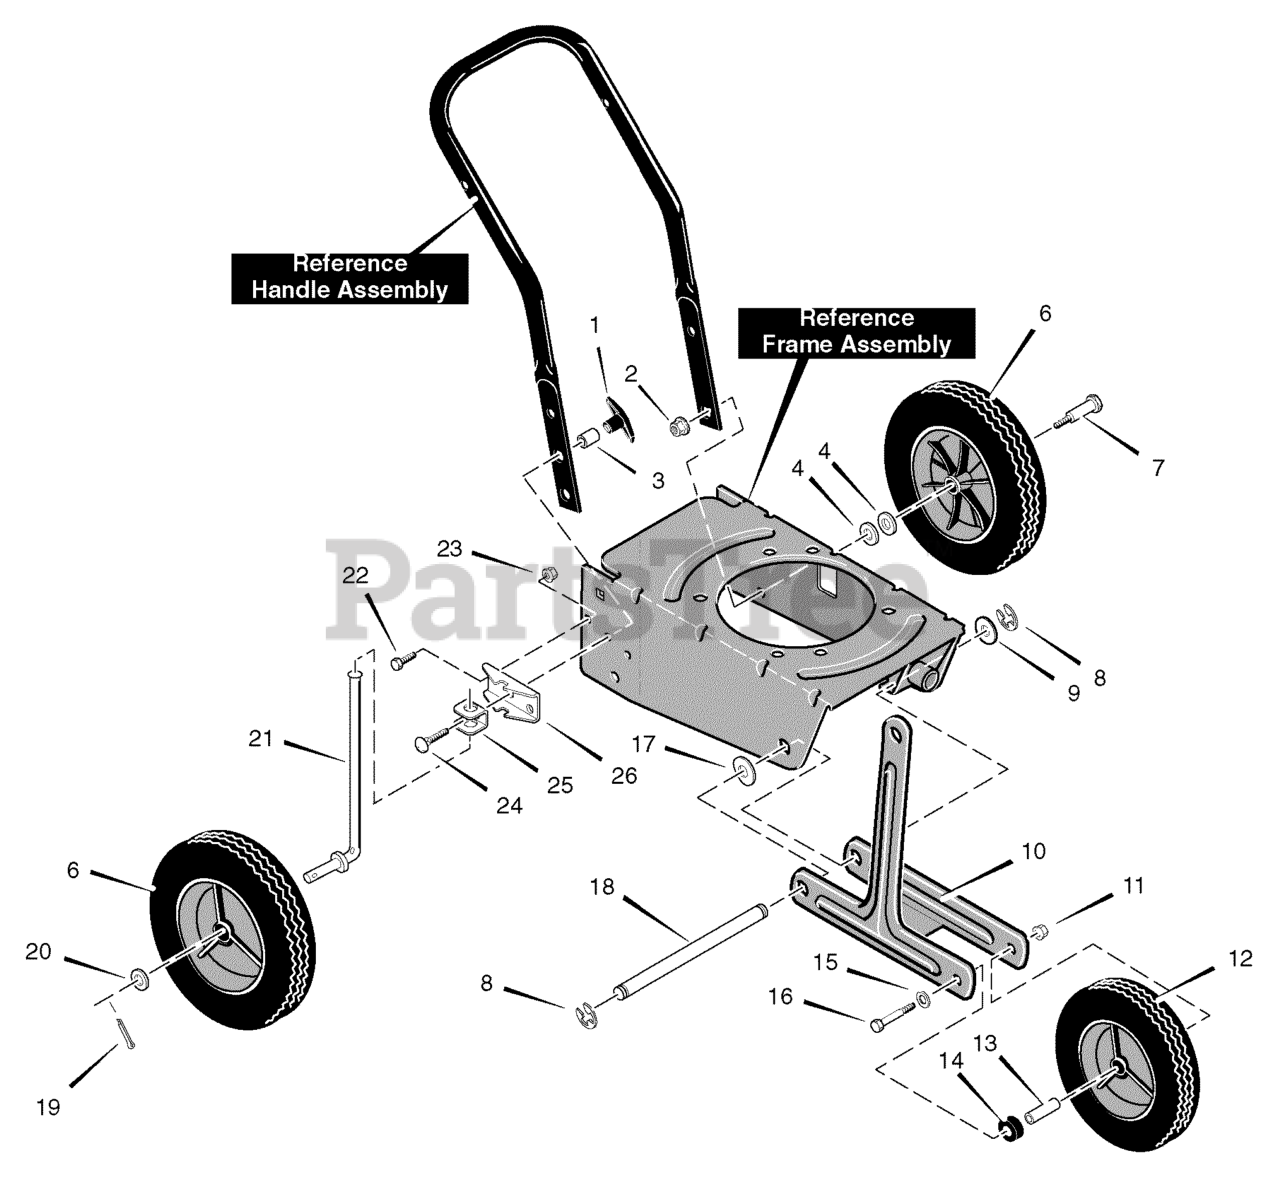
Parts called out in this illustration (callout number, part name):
1	Knob, Wing
2	Locknut, Flange
3	Spacer, Sleeve
4	Washer
6	Tire & Rim
7	Bolt, Shoulder
8	Ring, Ret E.
9	Flat washer
10	Arm, Front Wheel
11	NUT, 5/16-18
12	Tire & Rim
13	Spacer, Sleeve
14	Washer, Nylon
15	Flat washer
17	Spring Washer
18	Rod, Axle Front
19	Pin, Cotter
20	Washer
21	Rod, Wheel Support
22	Screw, 5/16-18 x 0.75
23	NUT, 5/16-18
24	Bolt, 5/16-18x2.00
25	Clevis
26	Bracket, Curb-Hop
